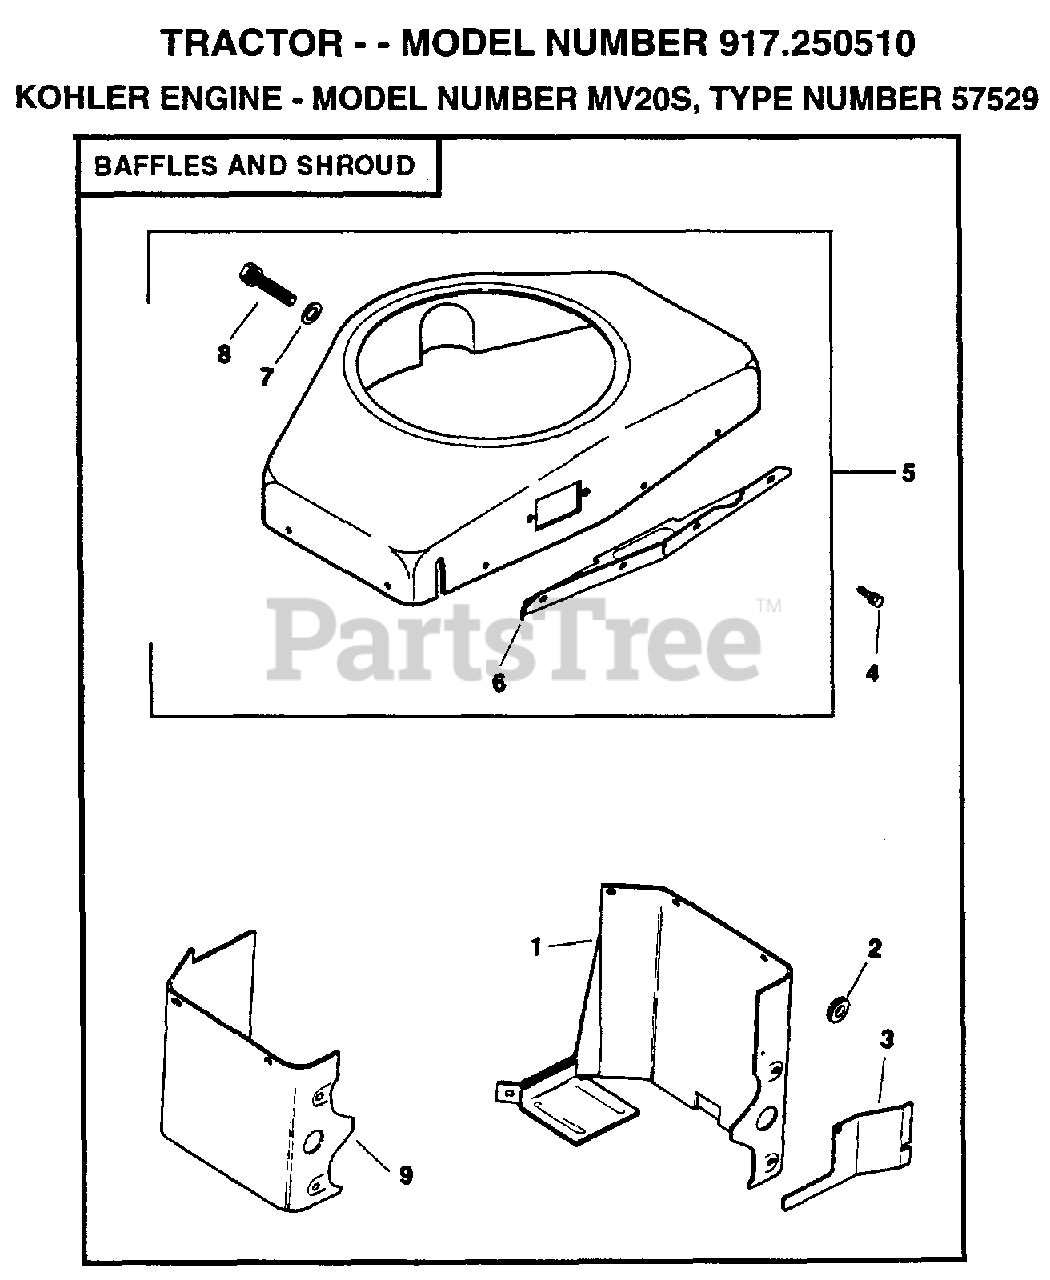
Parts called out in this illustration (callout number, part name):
3	BAFFLE, FUEL PUMP
4	SCREW
5	KIT, BLOWER HOUSING
6	SUPPORT, UPPER HOUSING
